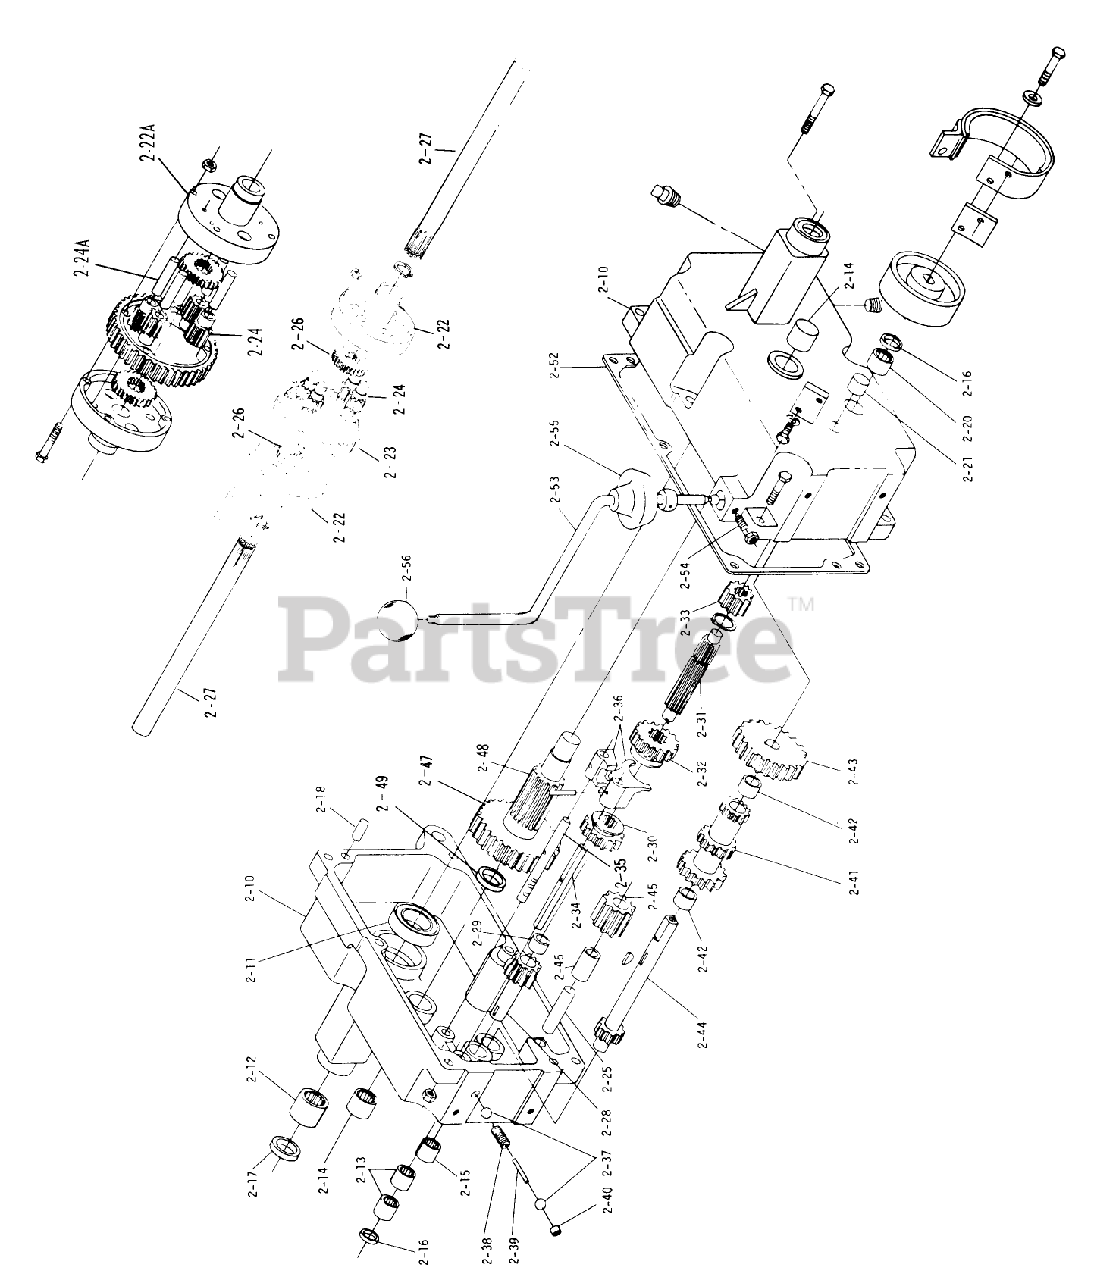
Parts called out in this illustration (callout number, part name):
2-12	BEARING-NEEDLE
2-14	BEARING-NEEDLE
2-15	BEARING-NEEDLE
2-16	SEAL-OIL
2-17	OIL SEAL
2-18	PIN-DOWEL
2-20	BEARING-NEEDLE
2-22	SVCBULLT 394
2-22A	DIFFERENTIAL CASE
2-23	SVC BULLT 394
2-24	GEAR-PINION, 11T
2-24A	PIN-DIFFERENTIAL
2-25	PIN-DIFFERENTIAL
2-26	AXLE GEAR
2-29	BEARING-NEEDLE
2-33	GEAR
2-34	RAIL-SHIFT
2-35	RAIL-REAR SHIFT
2-36	Fork-shaft
2-37	BALL-DETENT
2-39	PIN-SHIFT
2-40	CUP-PLUG
2-42	BUSHING-BRONZE
2-43	GEAR-CLUSTER SHAFT
2-45	GEAR/BUSHING ASM-REVERSE IDLER
2-46	BUSHING
2-48	PINION SHAFT
2-49	WASHER-THRUST
2-52	GASKET-TRANSMISSION
2-54	SETSCREW
2-55	COVER-DUST
2-56	SHIFT KNOB
